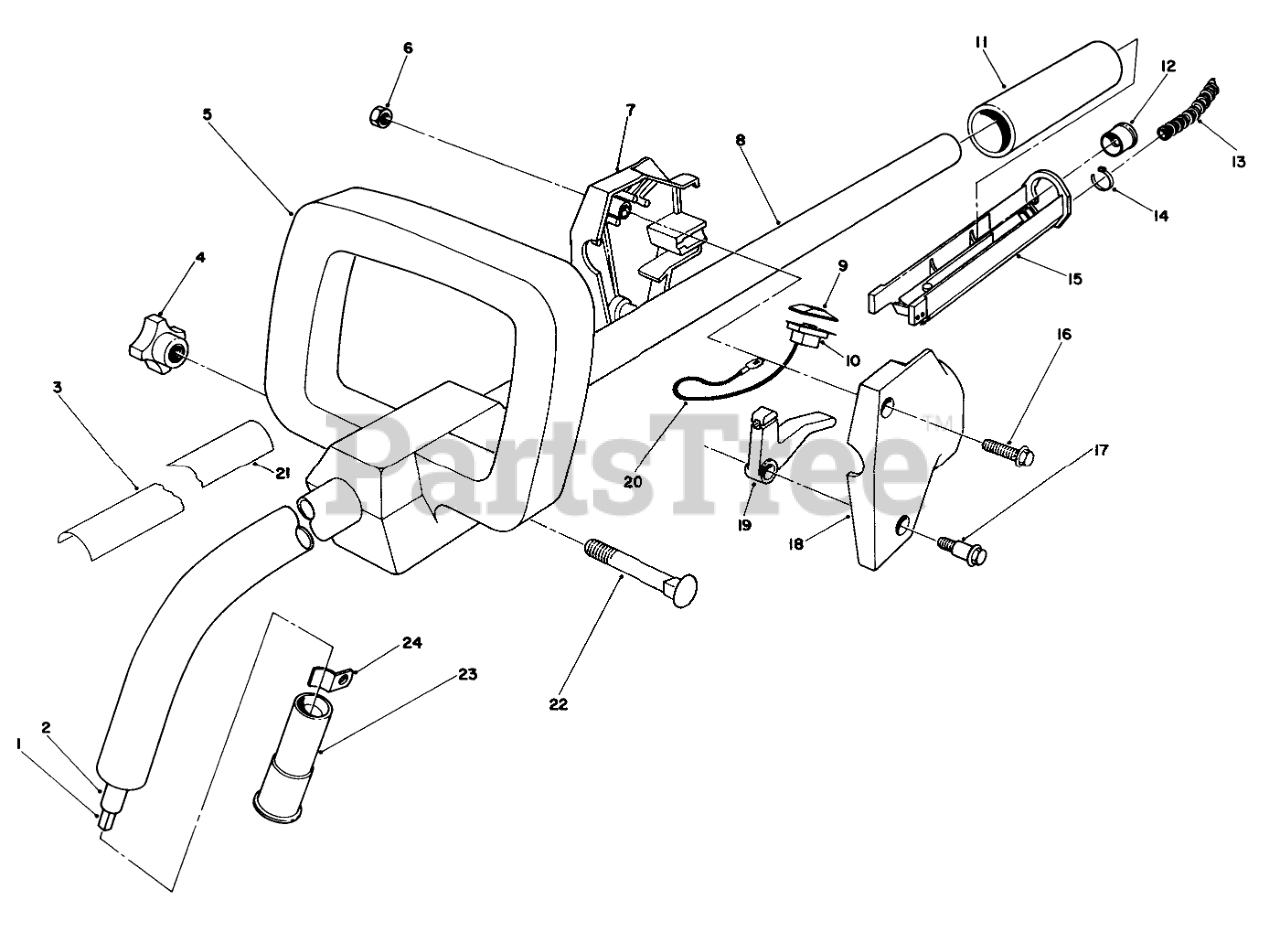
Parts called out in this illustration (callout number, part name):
1	FLEX SHAFT
2	FLEX SHAFT CASING ASM
3	Decal-Model No.
4	Knob
5	SECONDARY HANDLE
6	NUT-LOCK, NI
7	RH HOUSING
8	Tube-Curved
9	SWITCH COVER
10	SWITCH
11	GRIP-RUBBER
12	BUSHING
13	CABLE COVER
14	RING FITTING
15	TROUGH
17	SCREW-SHOULDER
18	LH HOUSING
19	THROTTLE LEVER
20	WIRE ASM
21	Decal
22	BOLT-CARRIAGE
23	INSERT-POLE END
24	LOWER TUBE RETAINER
